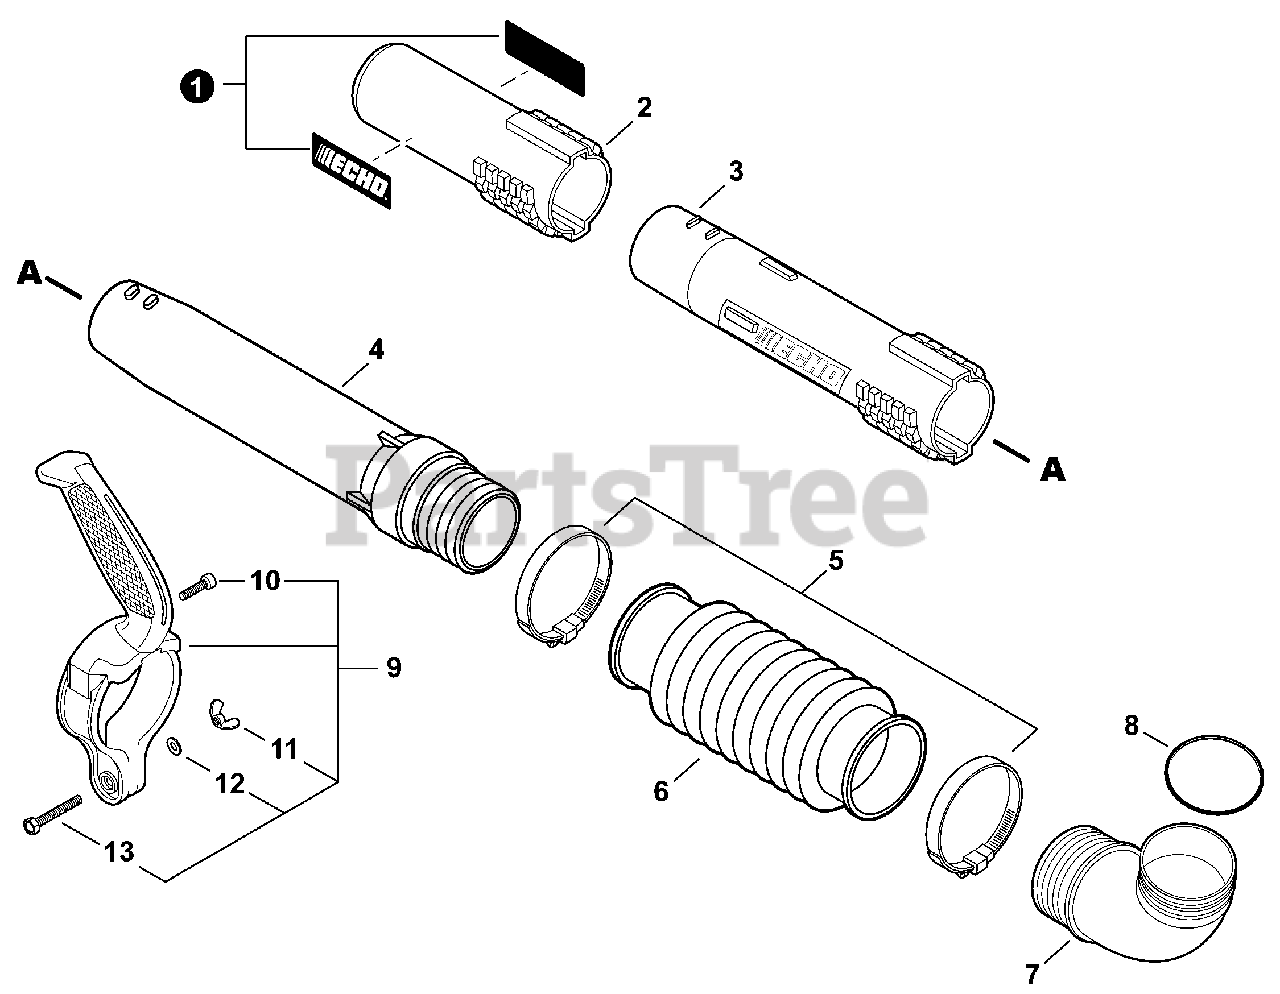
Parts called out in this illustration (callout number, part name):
1	LABEL, ECHO BLOWER TUBE
2	TUBE, NOZZLE 318×72/91
3	TUBE, BLOWER - STRAIGHT
4	TUBE, BLOWER - SWIVEL
5	CLAMP 77.8MM /101.6MM
6	TUBE, BLOWER - FLEXIBLE
7	TUBE, BLOWER - ELBOW
9	HANDLE ASSY, HELPER
10	BOLT, TORX 4×16
11	NUT, WING 6
12	WASHER 6.5×11.5×0.8
13	BOLT 6×25
